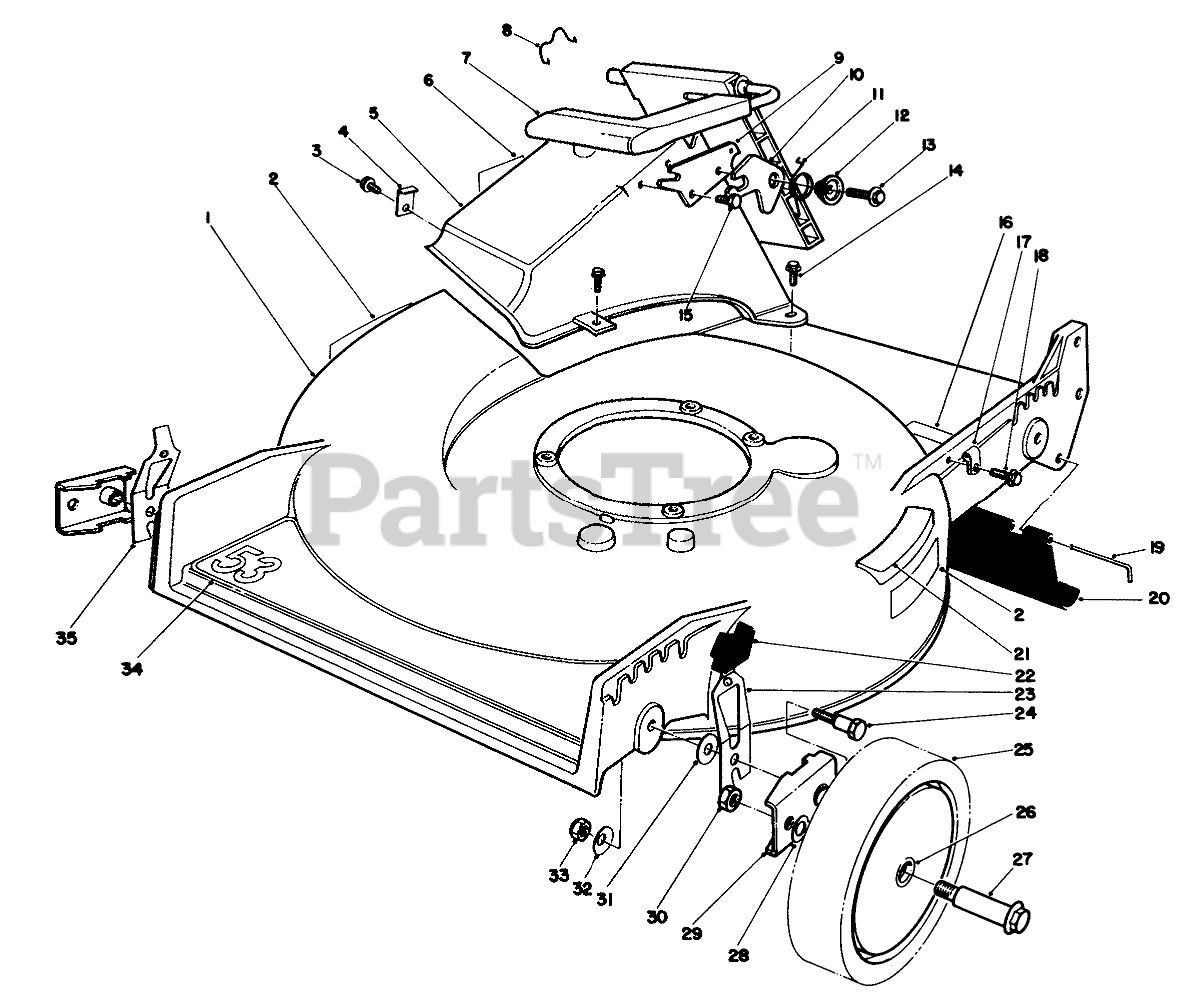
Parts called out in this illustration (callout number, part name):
1	Housing (Incl. Ref. #2)
2	Decal Danger
3	SCREW
4	TUNNEL CLIP
5	Tunnel Discharge
6	DECAL - DANGER
7	Discharge Door Assembly
8	DOOR RET SPRING
9	DOOR LATCH PLATE
10	SAFETY LATCH
11	TORSION SPRING
12	DOOR SPACER
13	SCREW-HWH
14	SCREW-HWH
15	SCREW-PLASTITE
16	Decal
17	CLAMP-CABLE
18	SCREW
19	ROD-SHIELD
20	SHIELD-TRAILING
21	DECAL - STEP PAD INT'L
22	KNOB-ARM
23	L. HP SPRING ARM ASM
24	PIVOT SCREW
25	Wheel & Tire Assembly (Inc. Ref. #27)
26	BUSHING
27	BOLT-WHEEL
28	WASHER
29	HP PIVOT ARM ASM
30	Nut
31	WASHER-PIVOT
32	WASHER-BELLEVILLE
33	NUT-LOCK, NI
34	Decal-53
35	R HP SPRING ARM ASM
